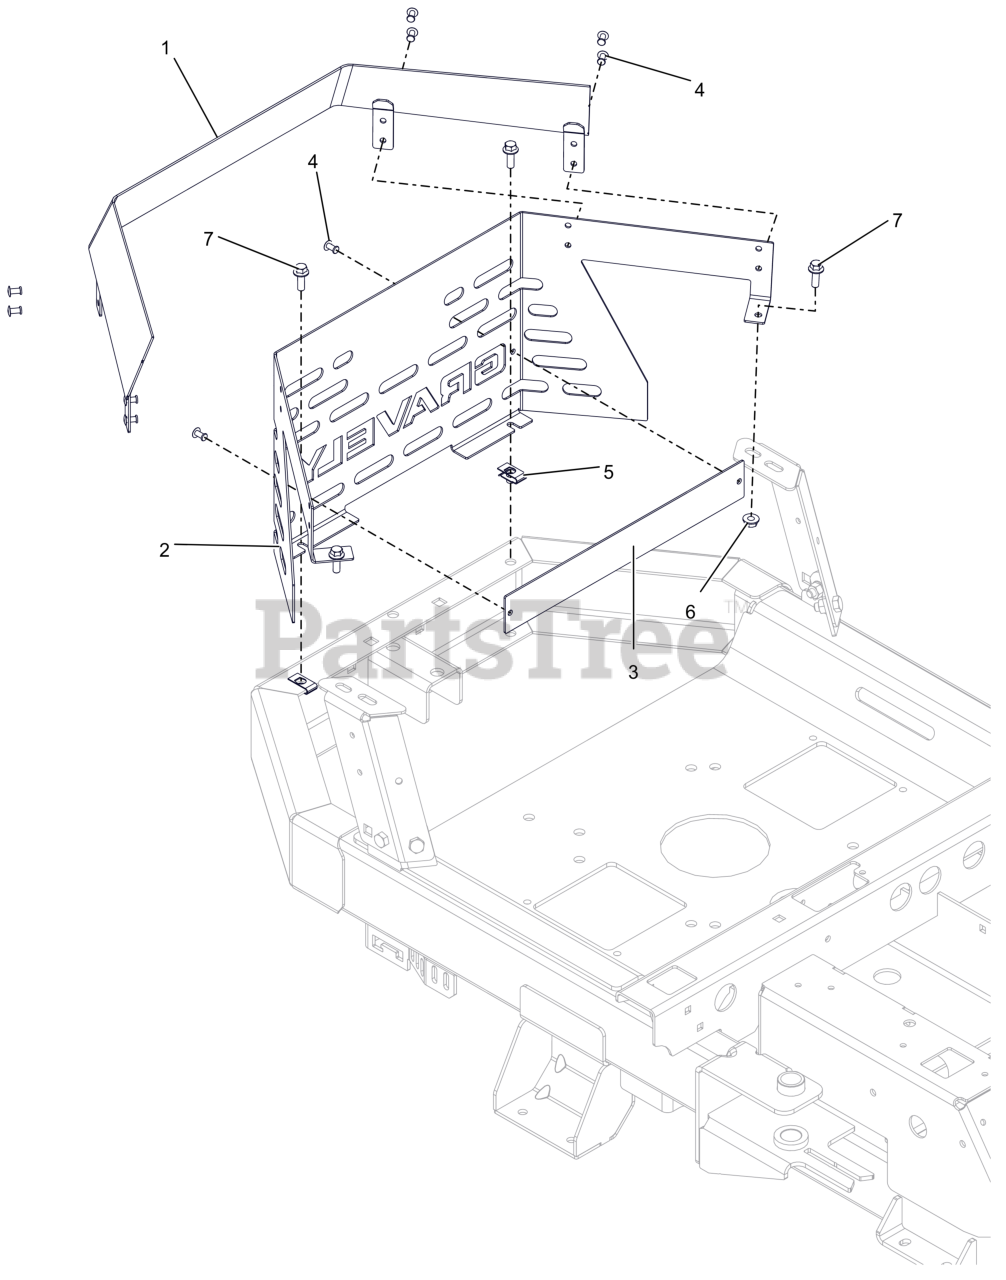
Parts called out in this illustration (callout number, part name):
1	BRACKET, ENGINE SHROUD TRIM
2	SHROUD, ENGINE GRAVELY
3	PLATE, SHROUD BACKER
4	RIVET, #66 STEEL POP PD BLACK
5	NUT-RTNR .25-20X.56
6	NUT-LK-TOP-FLG .250-20 GF ZCC
7	BLT,HEX-FLG .25-20X.75 G5 BFP
